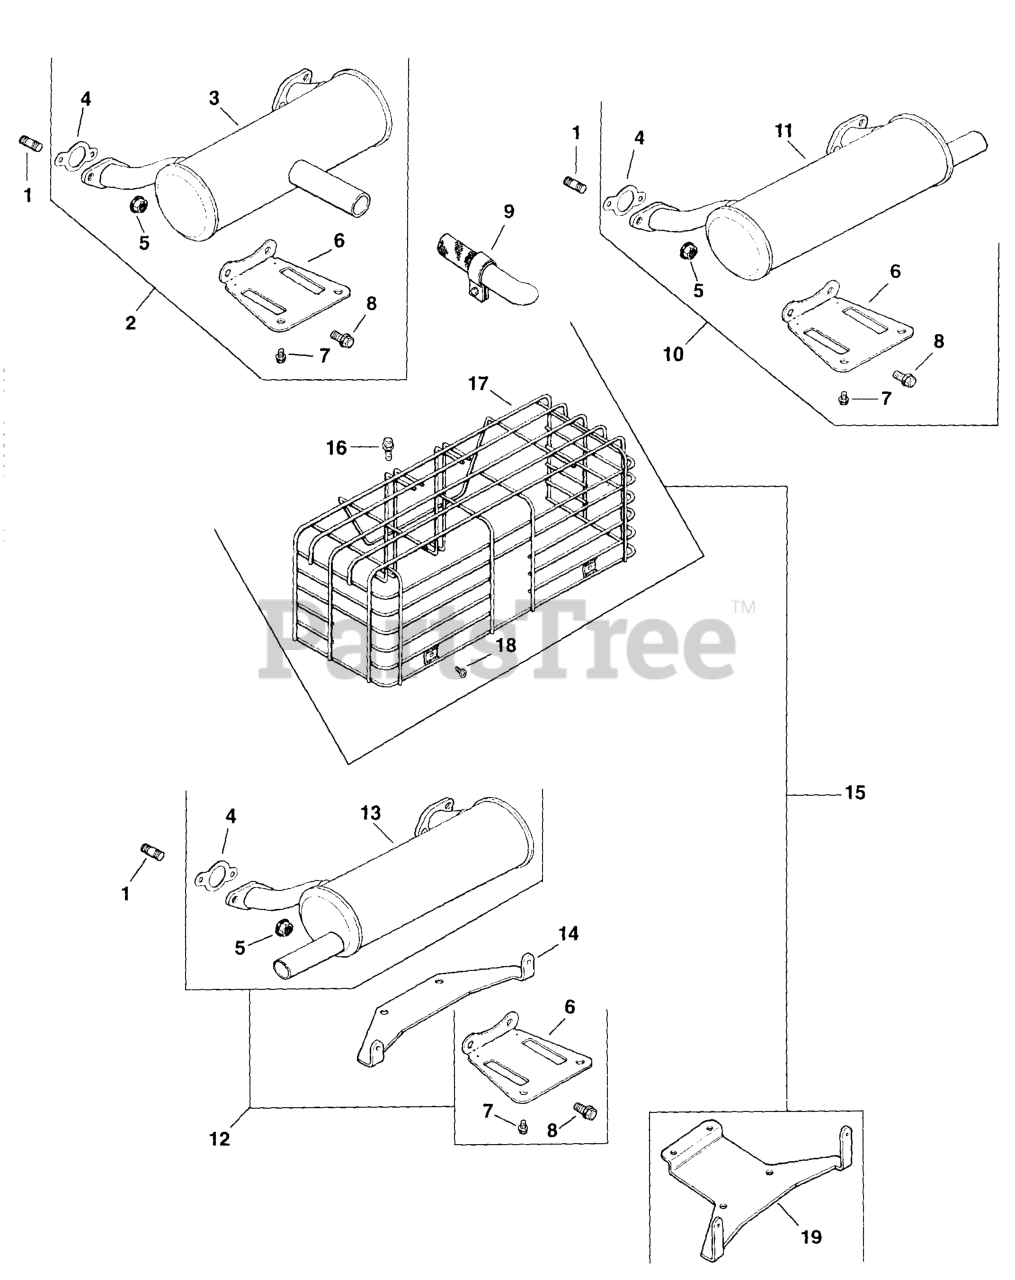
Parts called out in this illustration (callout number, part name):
1	STUD - USE M-829033
5	NUT - USE M-841080
6	BRACKET, MUFFLER
7	SCREW - USE M-650012
8	Screw, hex. flange M8x1.25x20
15	KIT, MUFFLER GUARD
16	SCREW - USE M-545016
17	GUARD, MUFFLER
18	SCREW - USE M-555010
19	BRACKET, EXHAUST GUARD
